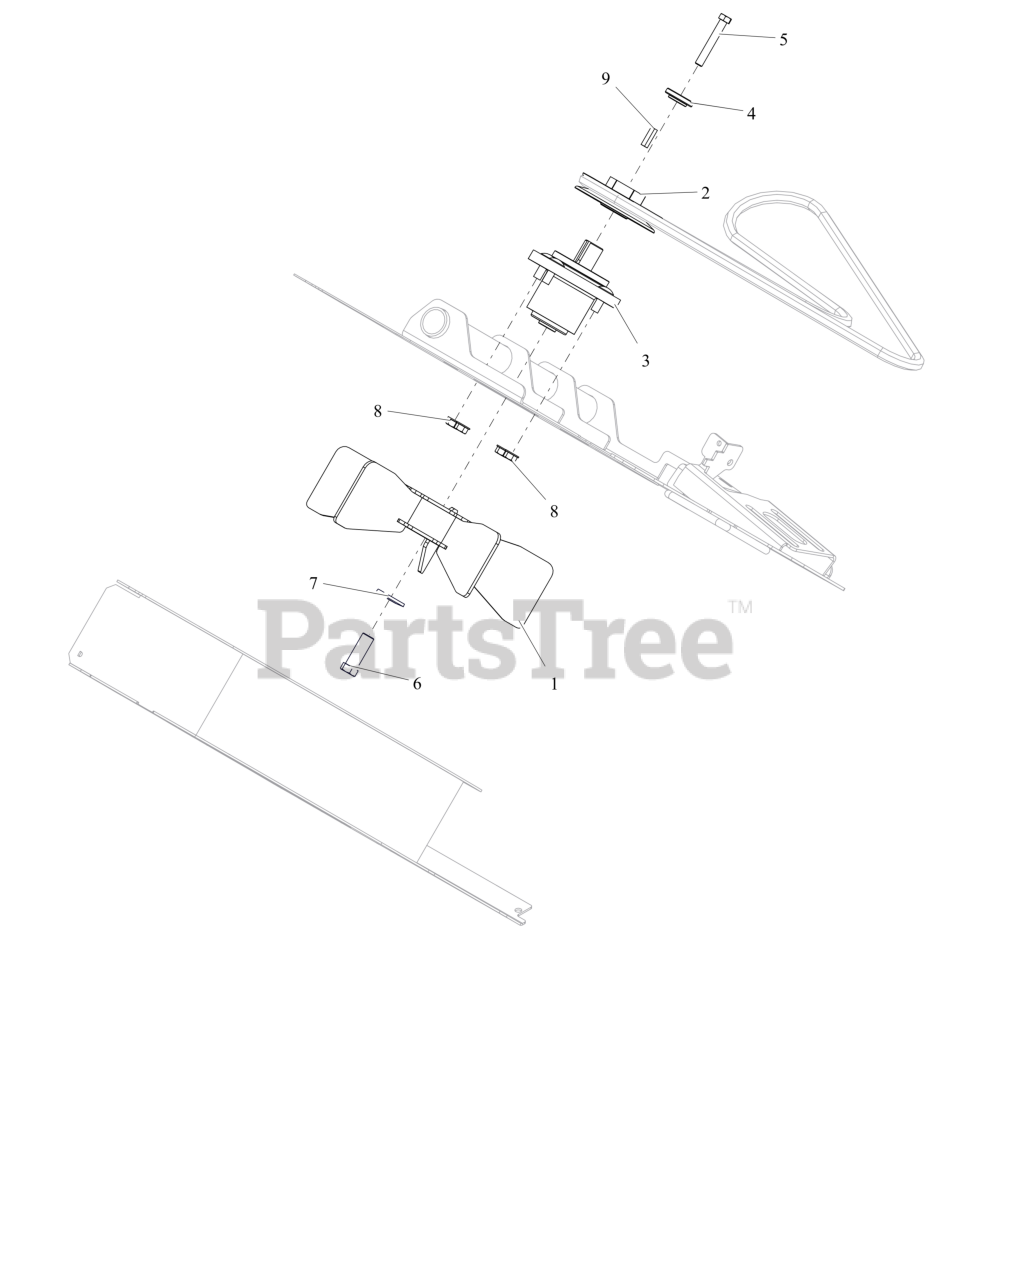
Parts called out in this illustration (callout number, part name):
1	IMPELLER, HD BLOWER
2	PULLEY, V-1.00"ID X 4.50" OD
3	SPINDLE, ASM HOUSING - ALUM. (BLOWER)
4	RETAINER, SHEAVE
5	BLT, HEX .38-16X2.50 G8 ZCC
6	BLT, HEX .62-18X1.75 G8 ZCC
7	WSHR-BLVL .669X1.535X.138
8	NUT-LK-TOP-FLG .38-16 ZC120
9	KEY, SQ .25X.25X1.00 RC 40-50
